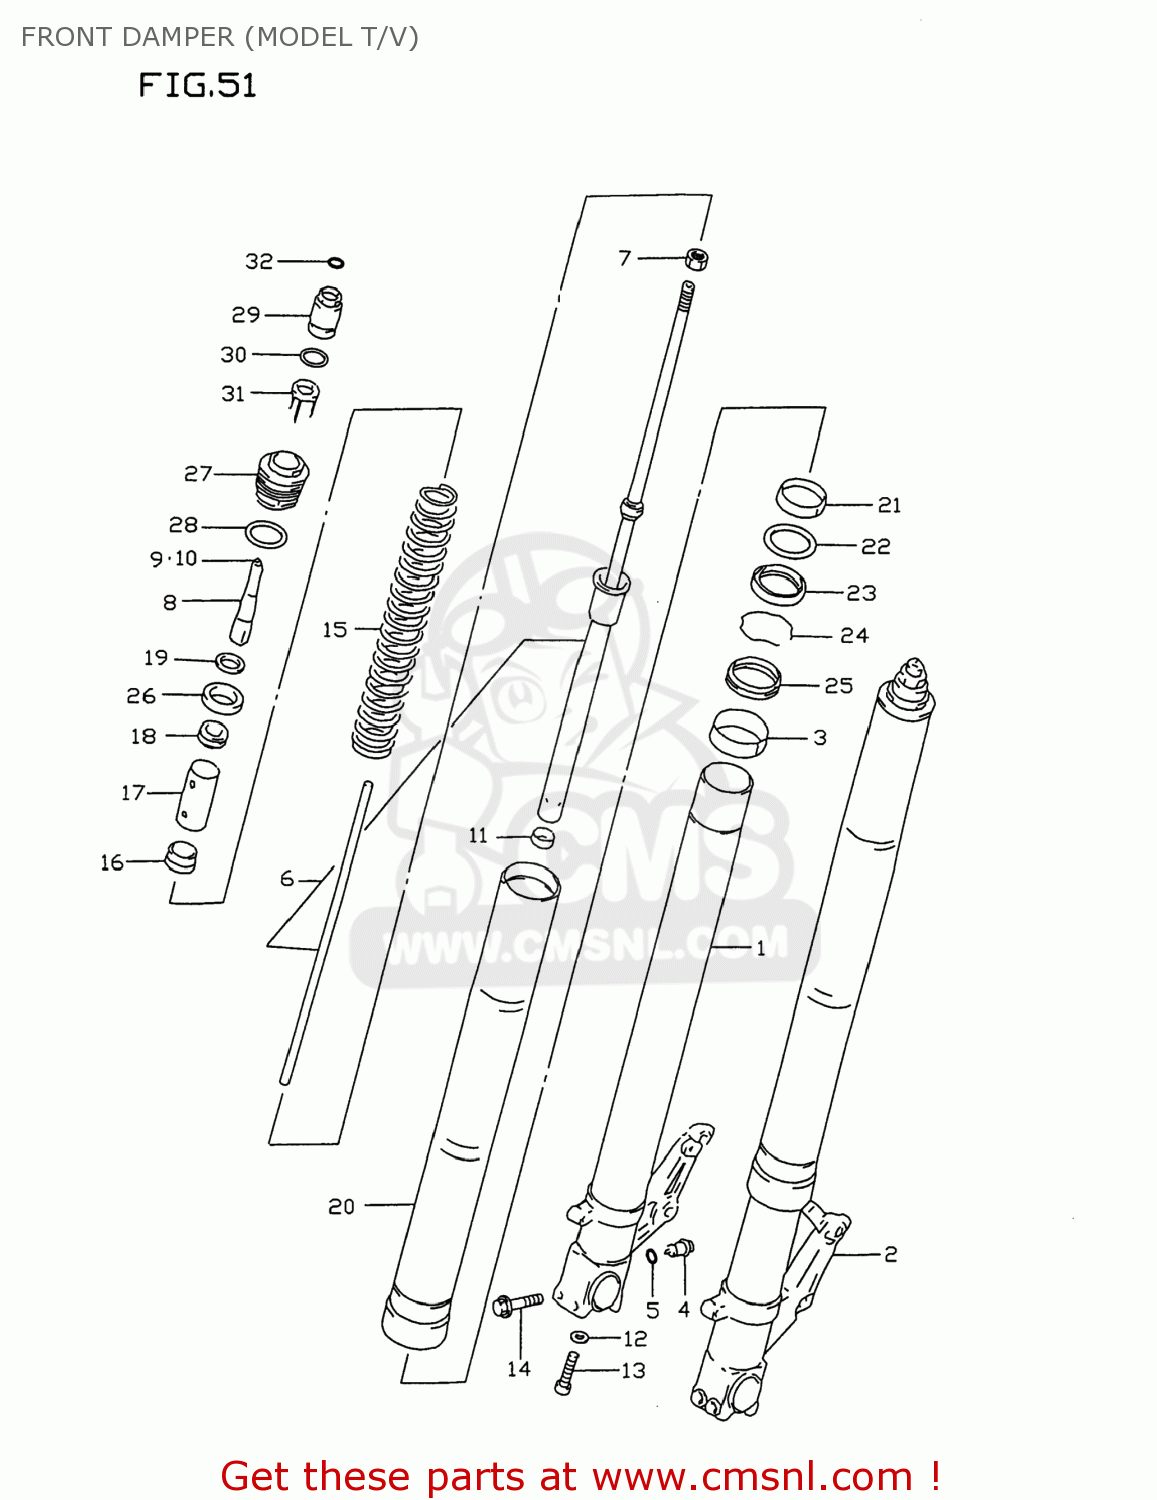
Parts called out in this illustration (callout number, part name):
1	TUBE,INNER,R
2	TUBE,INNER,L
3	BUSH,SLIDE
4	PIECE,ADJUST
5	O-RING (D:2.4 ID:13.8)
6	ROD,FRONT DAMPER
7	NUT
8	CASE,ADJUSTER
9	PIECE,ADJUST
10	O RING(D:1.9,ID:3.8)
11	PLATE,CENTERING
12	WASHER(10X15X1.5)
13	BOLT
14	BOLT
15	SPRING,MAIN
16	JOINT,SPRING
17	COLLAR,SPRING
18	GUIDE,SPRING UPR
19	GUIDE,SPRING
20	TUBE,OUTER
21	BUSH,GUIDE
22	SPACER,SEAL
23	SEAL,OIL
24	CIRCLIP,FORK OIL SEAL
25	SEAL,DUST
26	RUBBER,SEAT
27	BOLT,FORK
28	O RING,FORK BOLT
29	ADJUSTER,SPRING
30	O RING
31	PLATE,SPRING ADJUSTER
32	RING,STOPPER
